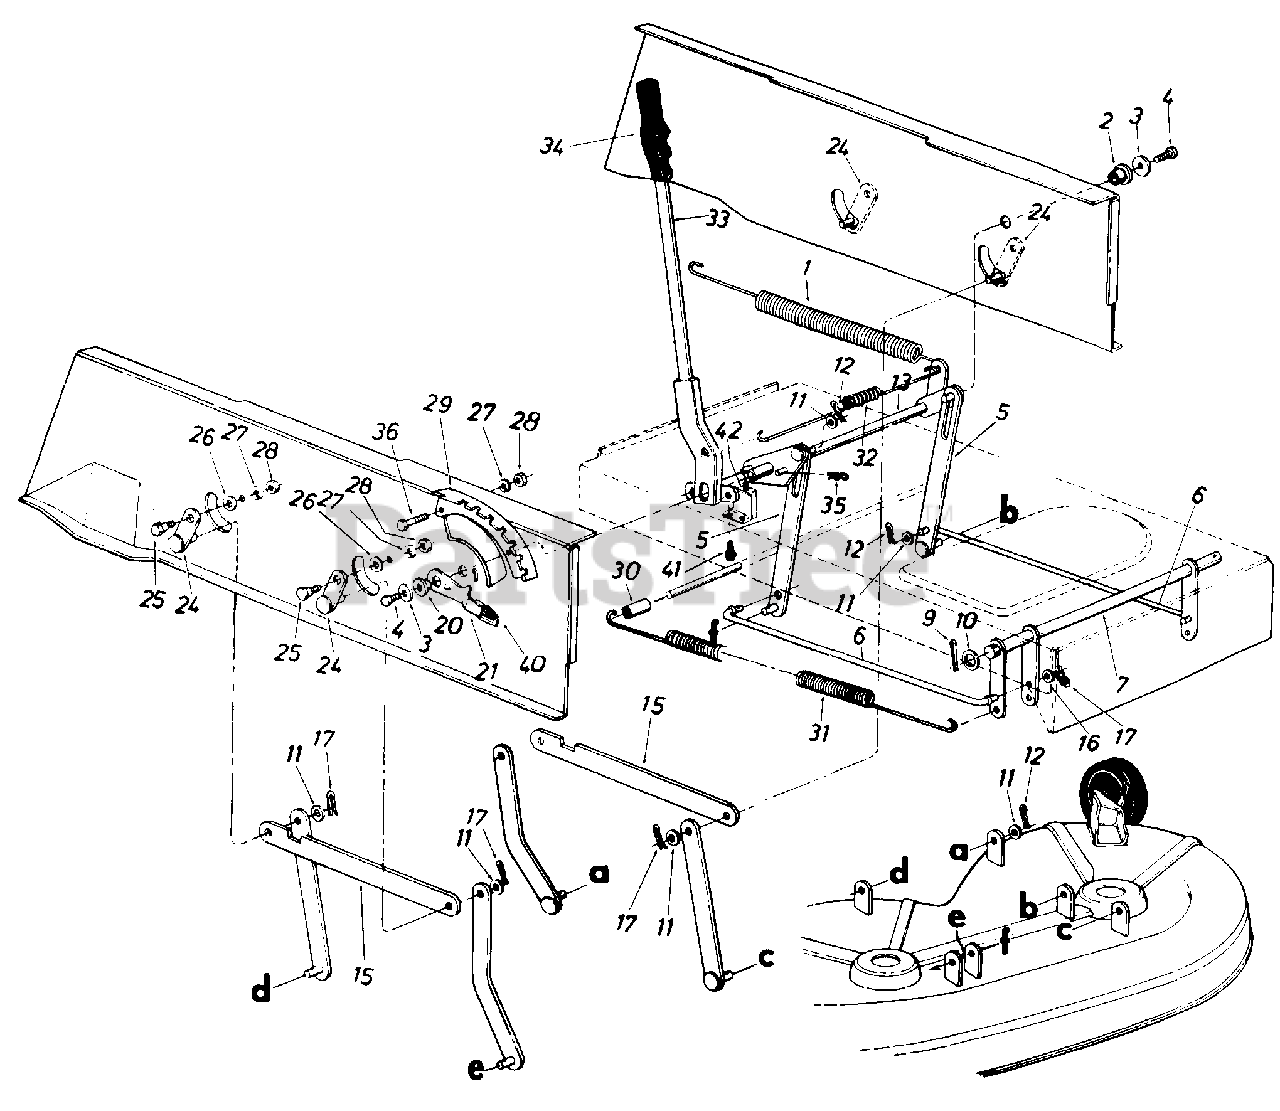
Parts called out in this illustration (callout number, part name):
1	Extension Spring .99" O.D. x 11.00" Lg.
2	Flange Bearing .634" I.D.
3	Fl-Wash. .344" I.D. x 1.125"
4	Hex Wash. Hd. 5/16-18 x .62" Lg.
5	Link Deck Lift Ass'y.
6	Stabilizer Rod
7	Stabilizer Shaft Ass'y.
9	Cotter Pin 1/8" Dia. x 1-1/4"*
10	Fl-Wash. .635" I.D. x 1.12"
11	Fl-Wash. .531" I.D. x .940"
12	Inter. Cotter Pin
13	Lift Shaft Ass'y.
15	Connecting Rod
16	Fl-Wash. .40" I.D. x .88"
17	Inter. Cotter Pin-3/8" Rod
20	Flange Brg. .630" I.D.
21	Deck Lift-Down Stop
24	Pivot Link Ass'y.
25	Shld. Bolt .437" Dia. x .180" Lg. (5/16-18)
26	Fl-Wash. .344" I.D. x .62"
27	L-Wash. 5/16" I.D.*
28	Hex Nut 5/16-18 Thd.
29	Index Brkt.
30	Spacer .523" I.D. x .640" O.D. x 1.95" Lg.
31	Ext. Spring .99" O.D. x 1 8.25" Lg.
32	Ext. Spring .56" O.D. x 32 Coils
33	Lift Handle Ass'y.
34	Grip
35	Intern. Cotter Pin 1/2" Dia.
36	Hex Bolt 5/16-18 x .75"*
40	Knob
41	Hex AB-Tap Scr. #10 x .50"
42	Safety Switch
